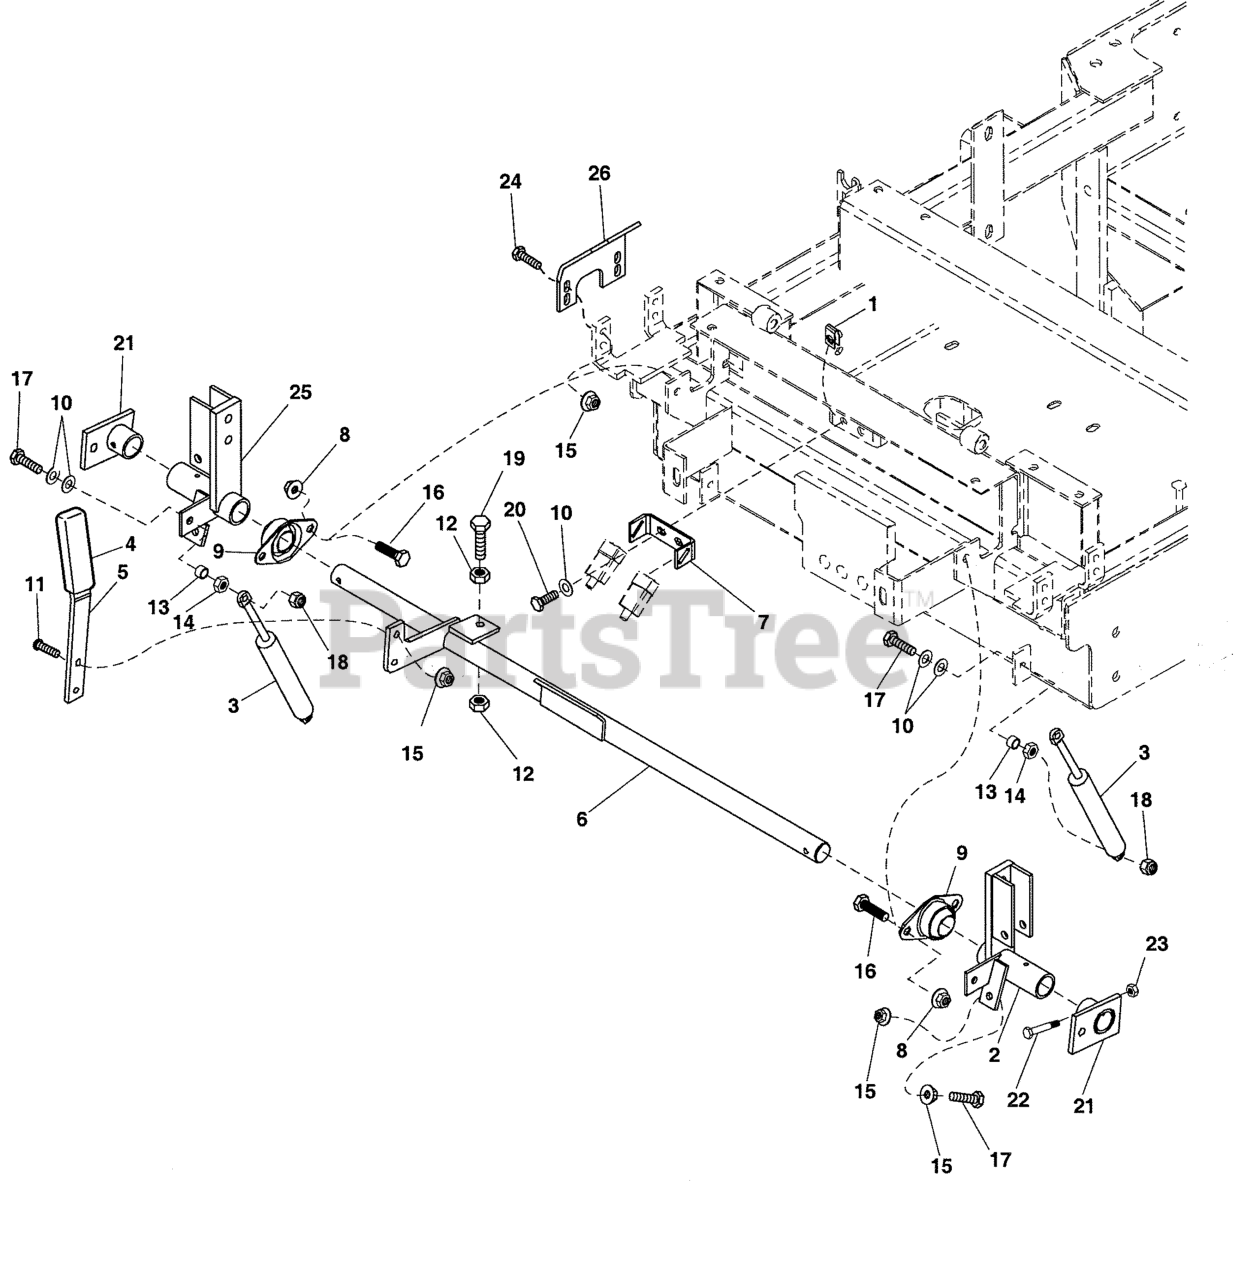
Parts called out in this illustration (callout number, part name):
1	BODY CLIP, 5/16-18-7GA MATERIAL
2	CONTROL ARM MOUNT, Left
3	DAMPENER
4	GRIP, FOAM, 1/4 X 1 X 4.1
5	BRAKE LEVER
6	BRAKE SHAFT
7	BRAKE SWITCH BRACKET
8	NUT, Hex, Serrated Flange 3/8-16
9	BEARING, Triangle
10	WASHER, 5/16" SAE
11	CAPSCREW, Button Socket Hd, 5/16-18 x 3/4
12	NUT, 3/8-16 HEX JAM
13	SPACER
14	NUT, 5/16-18 HEX
15	NUT, 5/16-18 HEX SERRATED FLANGE (SMALL)
16	BOLT, 3/8-16 X 3/4" GD5 CZ
17	BOLT, 5/16-18 x 1-1/2
18	NUT, HeX, Nylon Locking, 5/16-18
19	BOLT, 3/8-16 X 2, GD5, CZ
20	BOLT, 5/16-18 X 3/4 GD5
21	BRAKE LINKAGE
22	BOLT, 1/4-20 x 1-3/4
23	NUT, Hex, Side Locking, 1/4-20
24	BOLT, 5/16-18 X 1 GD5 YZ
25	CONTROL ARM MOUNT, Right
26	NEUTRAL PLATE, Right
